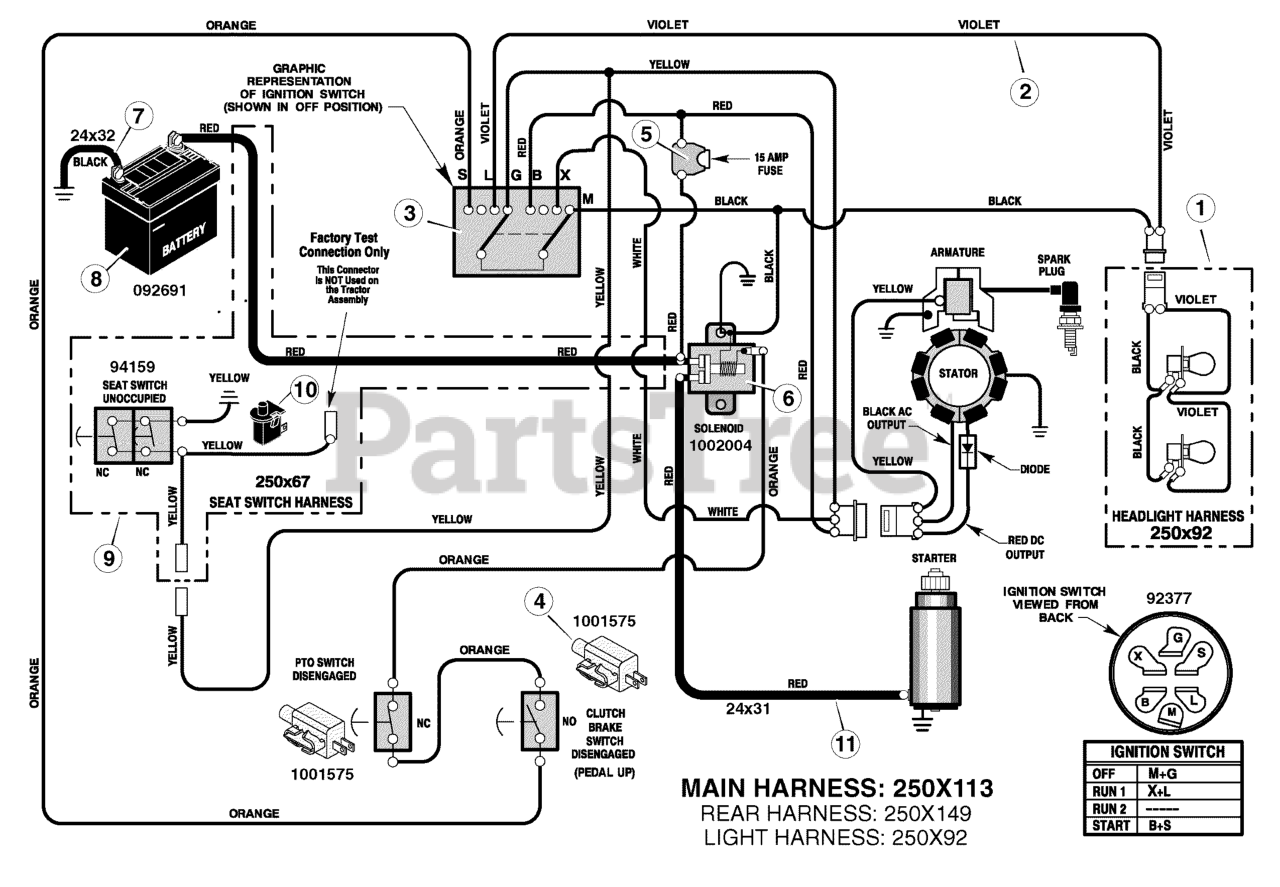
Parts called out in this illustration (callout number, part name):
1	Harness, Light Wire
1	Socket, Light
1	Bulb, Light
2	Harness, Chassis Wire
3	Switch, Ignition
3	Key, Ignition
3	Nut, Hex
3	Cap, Ignition
4	Switch, Limit
5	Holder, Fuse
6	Solenoid
6	Screw, Mounting
6	Locknut
7	Cable, Battery Ground
7	Screw, Ground Cable
8	Battery
8	Bolt, Carriage
8	Wingnut
8	BOOT, Battery Terminal, Positive
9	Harness, Seat Switch Wire
10	Switch, Seat Sensor
